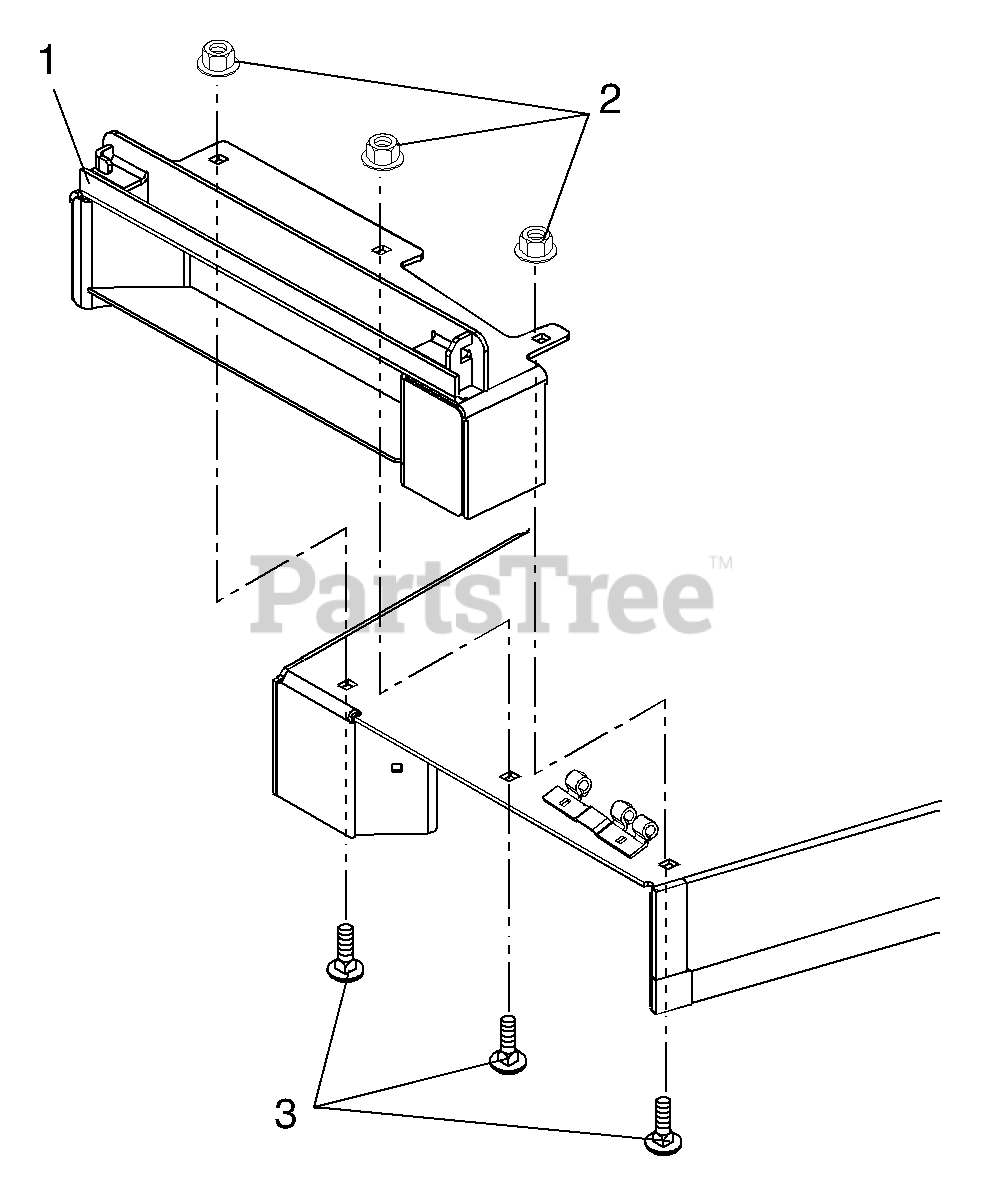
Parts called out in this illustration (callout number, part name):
1	WMT,BAGGER EXT BRK ZOOM-40/44
2	NUT-LK-TOP-FLG .38-16 BLKZC
3	BLT-RDHDSQNK .38-16X.75 G5BZ
